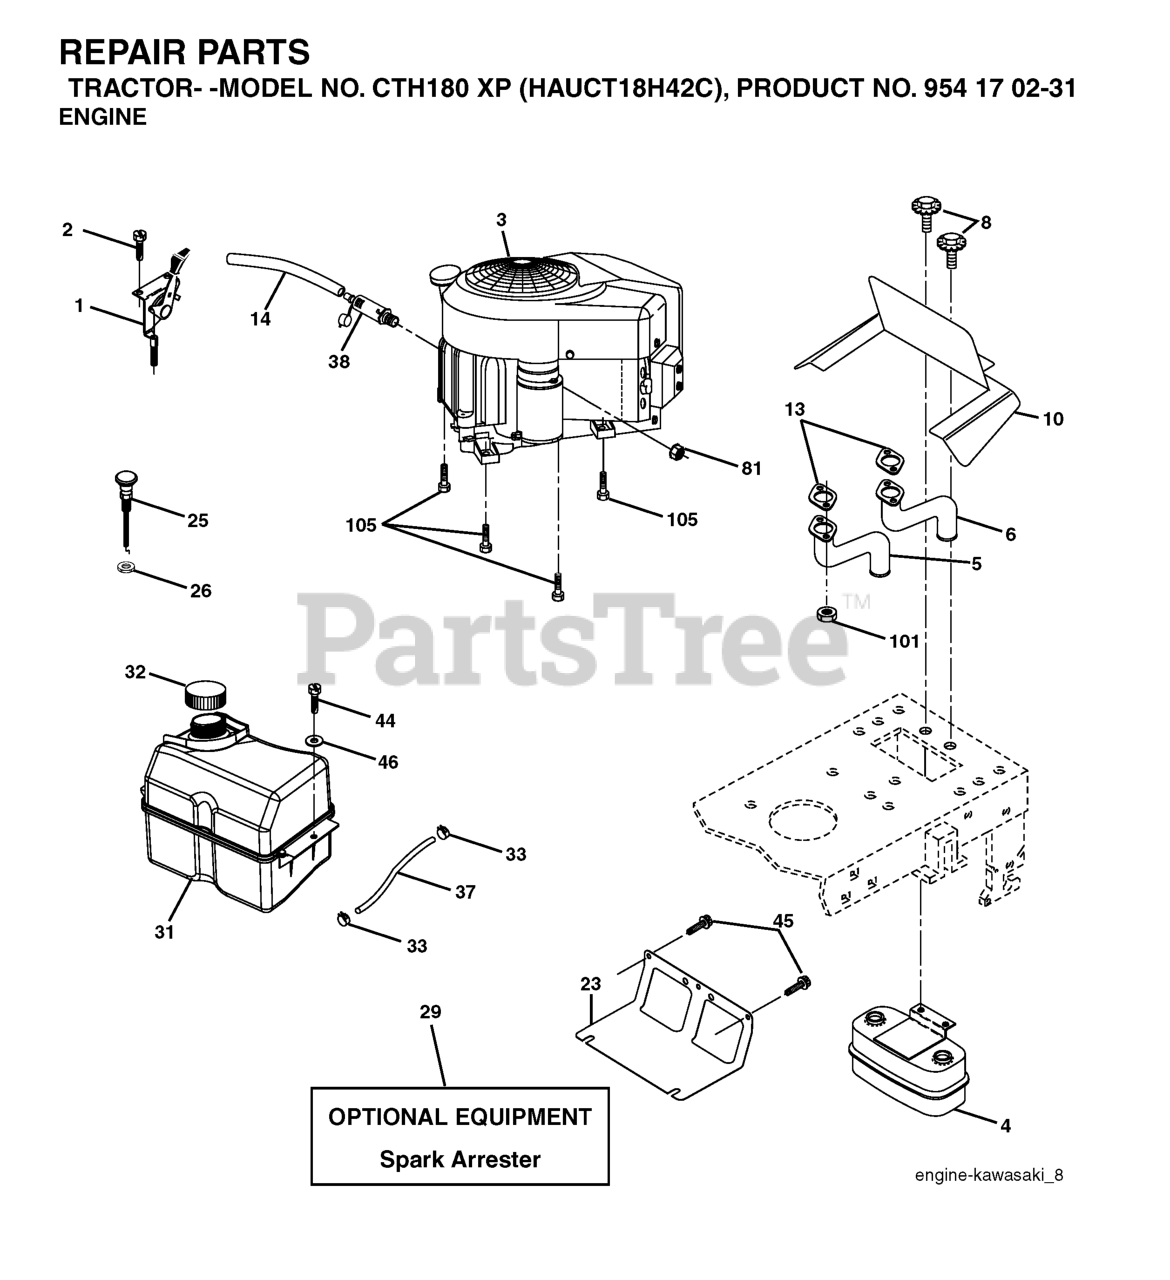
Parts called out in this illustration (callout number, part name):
1	THROTTLE CABLE
2	SCREW
4	MUFFLER.TWIN.CYL.LOW.TONE
5	EXHAUST.TUBE.LH.KAWASAKI.
6	EXHAUST.TUBE.RH.KAWASAKI.
8	BOLT.5/16-18UNCX3/4 W/SEMS.BLK
10	RP SHIELD HEAT MUFFLER
14	TUBE, DRAIN OIL ASM.
23	SHIELD.BROWNING.DBR.GUARD
25	REPL BY 532 1754-40
26	Nut Keps 3/8 - 24 UNF
29	KIT.SPARK ARRESTOR 794945 B&S
31	FUEL TANK
32	FUEL CAP
33	HOSE CLAMP
37	LINE.FUEL.20
44	SCREW HEXWSHR 1/4-20X3/4
45	SCREW, 3/8-16X3/4
81	NUT
101	NUT.HEX.FLANGE.TOPLOCK
105	SCREW 3/8-16X1
